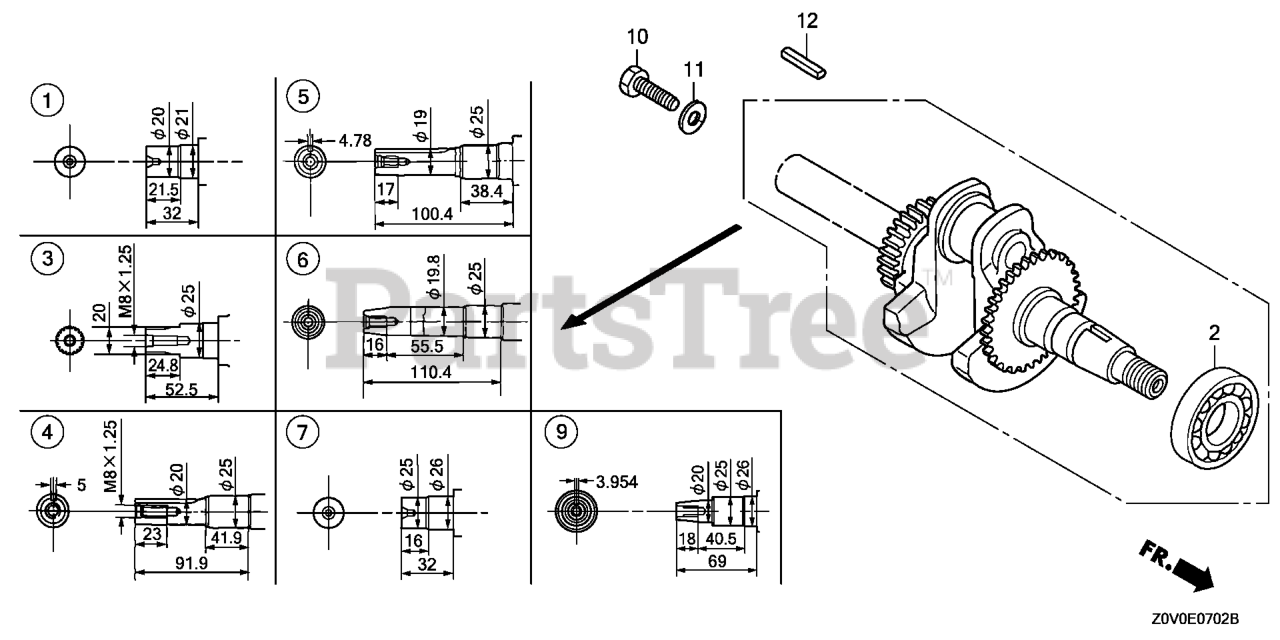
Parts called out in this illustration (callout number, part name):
2	BEARING, RADIAL BALL (6205)
2	BEARING, RADIAL BALL (6205) (NSK)
5	CRANKSHAFT
